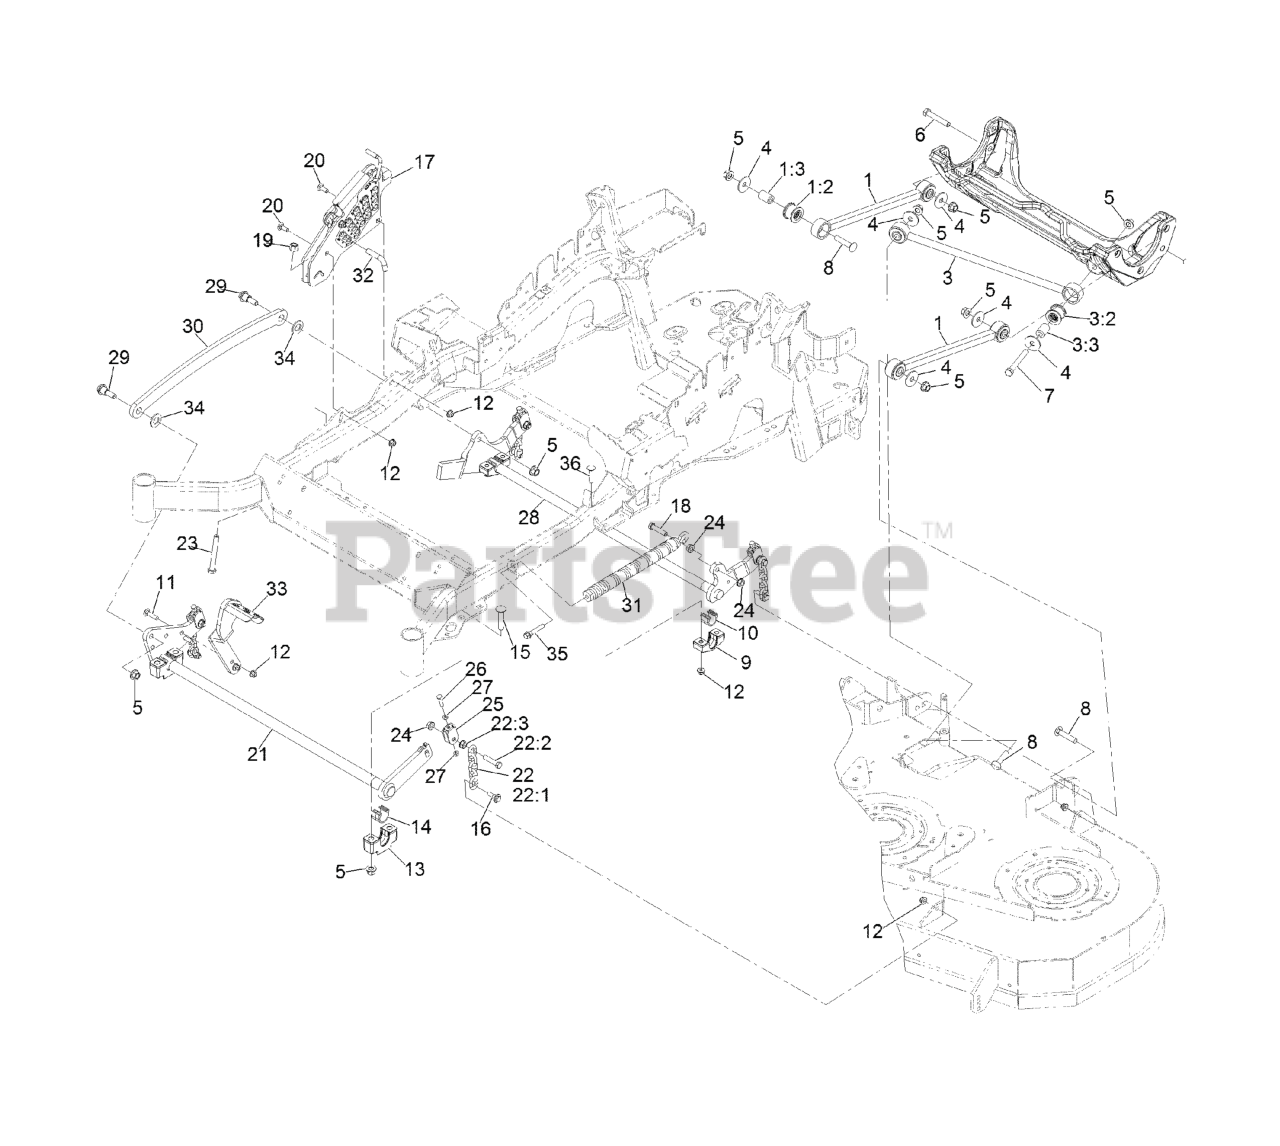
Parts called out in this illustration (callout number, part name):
1	LONG STRUT ASM
1:2	BUSHING-SUSPENSION, RUBBER
3	PANHARD ROD ASM
3:2	BUSHING-SUSPENSION, RUBBER
4	WASHER-THRUST
5	Nut-Lock 1/2-13
6	SCREW-HH
7	SCREW-HH
8	SCREW-CARR
9	SUPPORT-CROSS SHAFT, BEARING REAR
10	BEARING-CROSS SHAFT, REAR
11	SCREW-CARR
12	NUT-HF, NI
13	SUPPORT-CROSS SHAFT, BEARING
14	BEARING-CROSS SHAFT, FRON
15	Bolt-Carriage 1/2-13 X 2 1/2 Spl Neck
16	SCREW-SHOULDER, HHF
17	HOC ASM
18	SCREW-HH
19	NUT-LOCK, NI
20	BOLT-CARR
21	DECKLIFT-FRONT
22	DECK LIFT CHAIN ASM
22:1	CHAIN-LIFT, DECK
22:2	SCREW-HH
23	BOLT-TAP
25	YOKE-ADJUST, DECK
26	SCREW-HH
27	NUT-JAM
28	LIFT-DECK, REAR
29	SCREW-SHOULDER, HHF 1/2-13 X 1.12
30	LINK-LIFT, DECK
31	SPRING-EXTENSION
32	PIN-HOC
33	LEVER-FOOT
34	WASHER-FLAT
35	BOLT-SHOULDER
36	Bolt-Carriage 3/8-16 X 2 1/4
